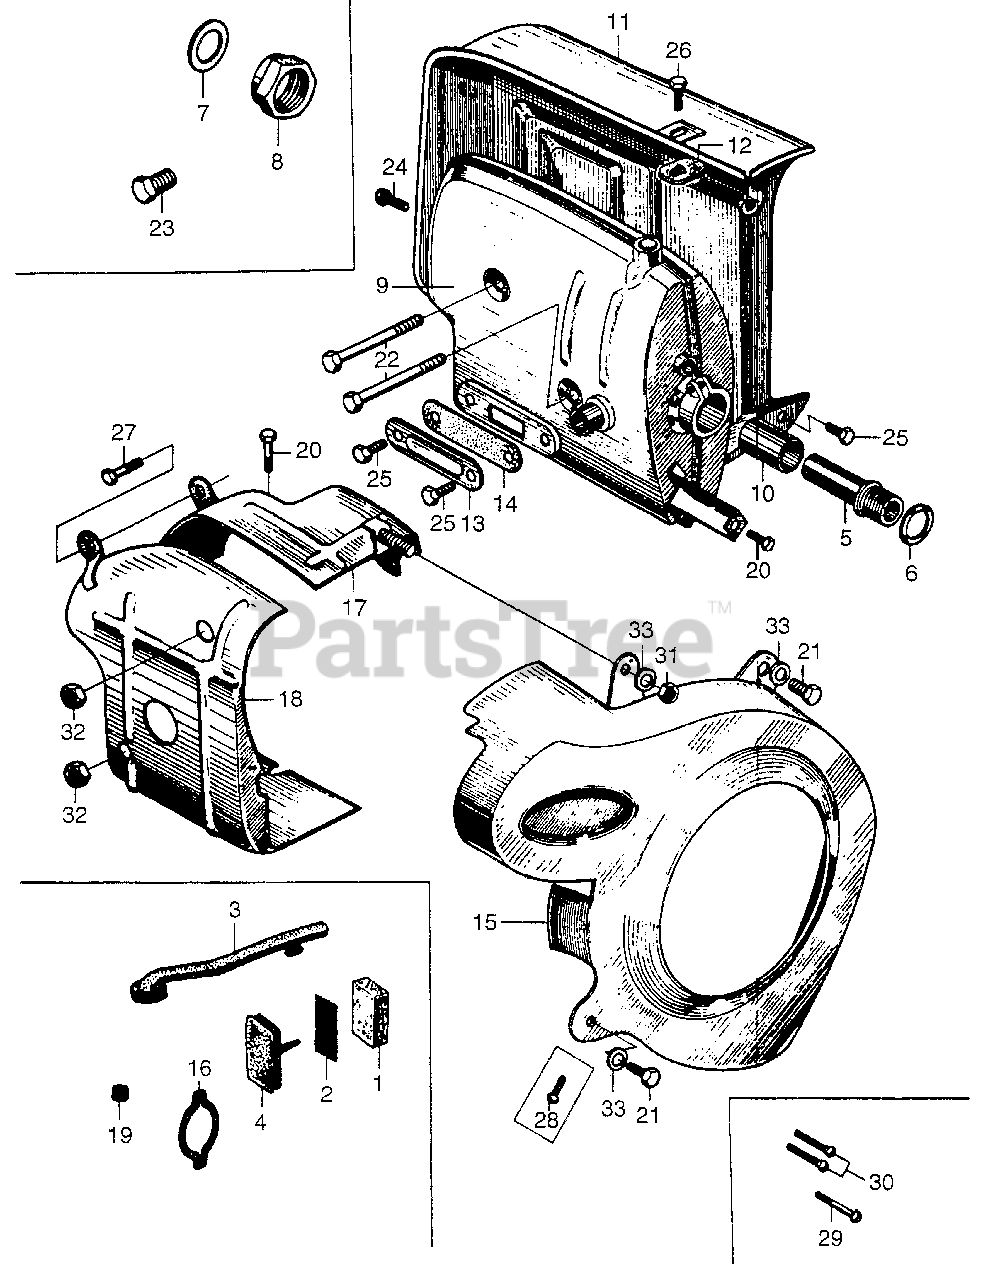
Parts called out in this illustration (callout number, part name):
5	PIPE, EX. (NOT AVAILABLE)
6	GASKET, EX. PIPE (NOT AVAILABLE)
9	MUFFLER (NOT AVAILABLE)
10	SEAL, EX. PIPE (NOT AVAILABLE)
11	PROTECTOR, MUFFLER
12	STOPPER, PROTECTOR
13	LID, MUFFLER
14	GASKET, MUFFLER LID (NOT AVAILABLE)
15	COVER, FAN (NOT AVAILABLE)
17	VANE A, GUIDE
18	VANE B, GUIDE
20	BOLT, HEX. (5X8)
21	BOLT, HEX. (5X8)
22	BOLT, MUFFLER SET
23	BOLT, HEX. (5X18)
24	BOLT, HEX. (5X14)
25	BOLT, HEX. (5X10)
25	NUT, HEX. (5MM)
26	BOLT, HEX. (5X14)
27	BOLT, RECESSED (5X8)
31	NUT, HEX. (5MM)
32	NUT, HEX. (6MM)
33	WASHER, PLAIN (5MM)
